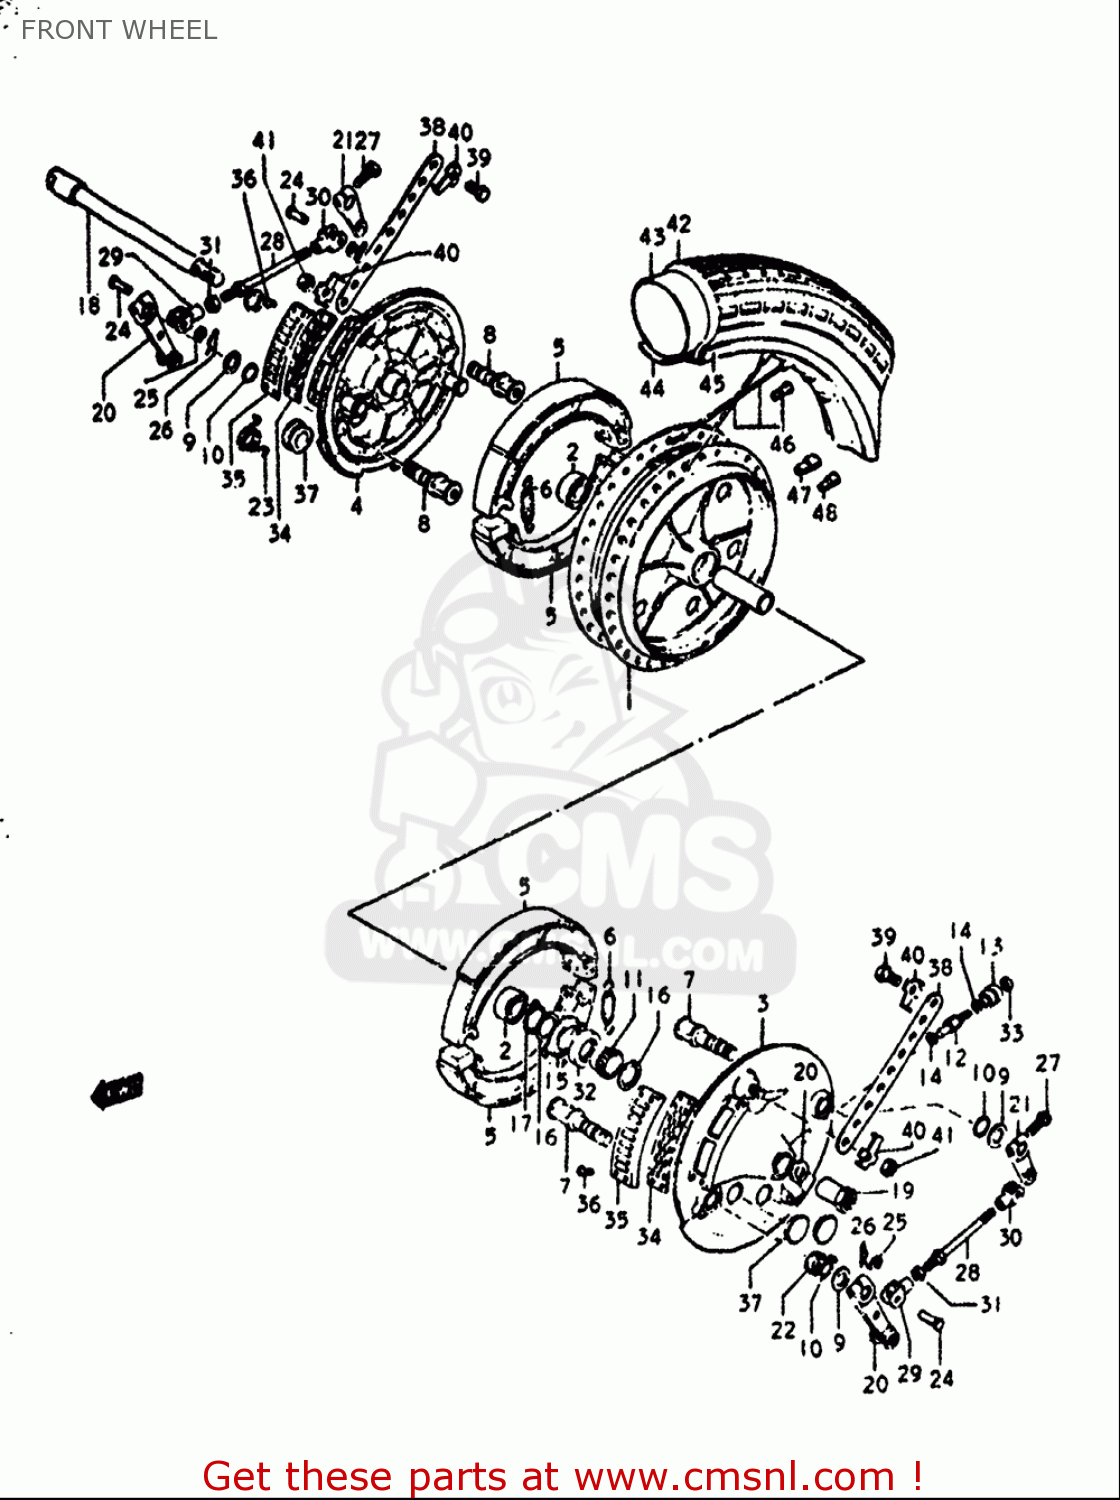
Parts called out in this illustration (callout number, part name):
2	BEARING
5	SHOE SET,FR BRAKE (NAS)
6	SPRING,BRAKE SHOE
9	WASHER(15.5X24X1.6)
10	O RING(D:2.4,ID:14.8)
12	PINION,SPEEDOMETER
13	BUSHING,SPEEDOMETER PINION
14	WASHER(5.1X9X0.4)
15	DRIVER,SPEEDOMETER GEAR
16	WASHER(22.5X27X1)
17	CIRCLIP
22	SPRING
25	WASHER
26	PIN 12X10
27	BOLT
31	NUT
32	SEAL,OIL(26X38X4)
33	SEAL,OIL(6X10X3)
36	SCREW
41	NUT
43	TUBE ASSEMBLY,WHEEL,INNER
44	PROTECTOR,WHL INR TUBE
45	RIM,WHEEL
47	BALANCER,WHEEL (30G)
48	BALANCER,WHEEL (B)
